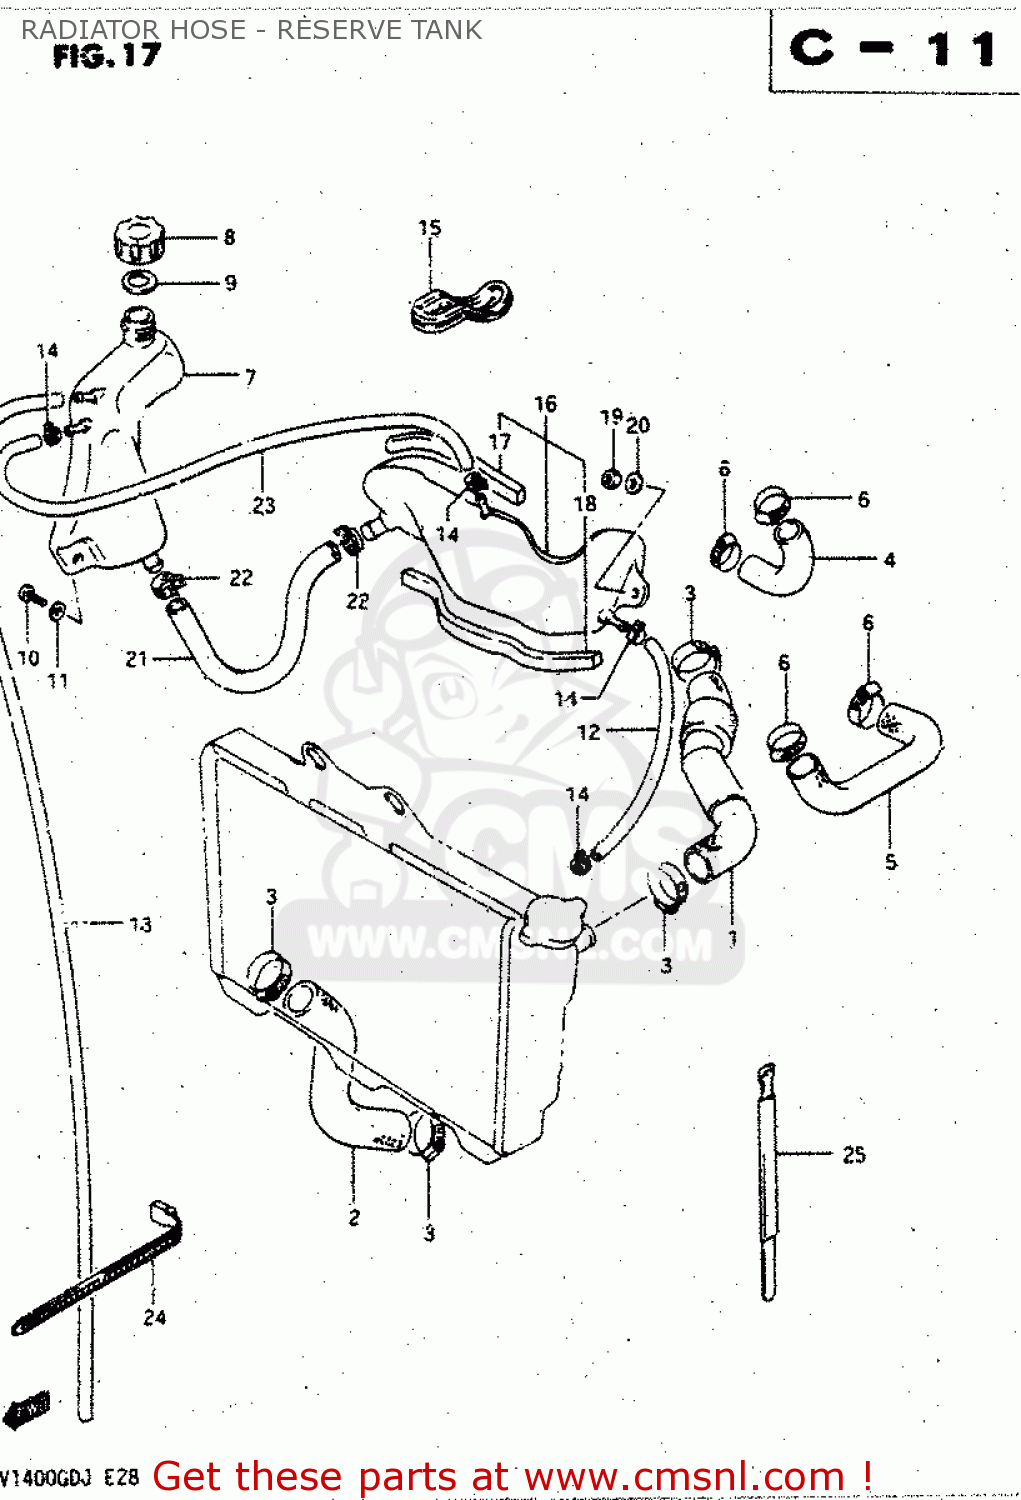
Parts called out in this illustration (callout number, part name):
1	HOSE,RADIATOR INLET
2	HOSE,RADIATOR OUTLET
3	CLAMP
4	HOSE,THERMO IN FR
5	HOSE,THERMO IN RR
6	CLAMP
7	TANK,RESERVE
8	CAP,RESERVOIR TANK
9	GASKET,RESERVOIR TANK CAP (NAS)
10	SCREW
11	WASHER
12	HOSE
13	HOSE (5X10X980)
14	CLIP
15	GROMMET
16	TANK,RESERVOIR NO.2
17	CUSHION,RESERVOIR NO.1
18	CUSHION,RESERVOIR NO.2
19	NUT 6MM
20	WASHER
21	HOSE,RESERVOIR INLET
22	CLAMP
23	HOSE
24	CLAMP(L:165)
25	CLAMP
